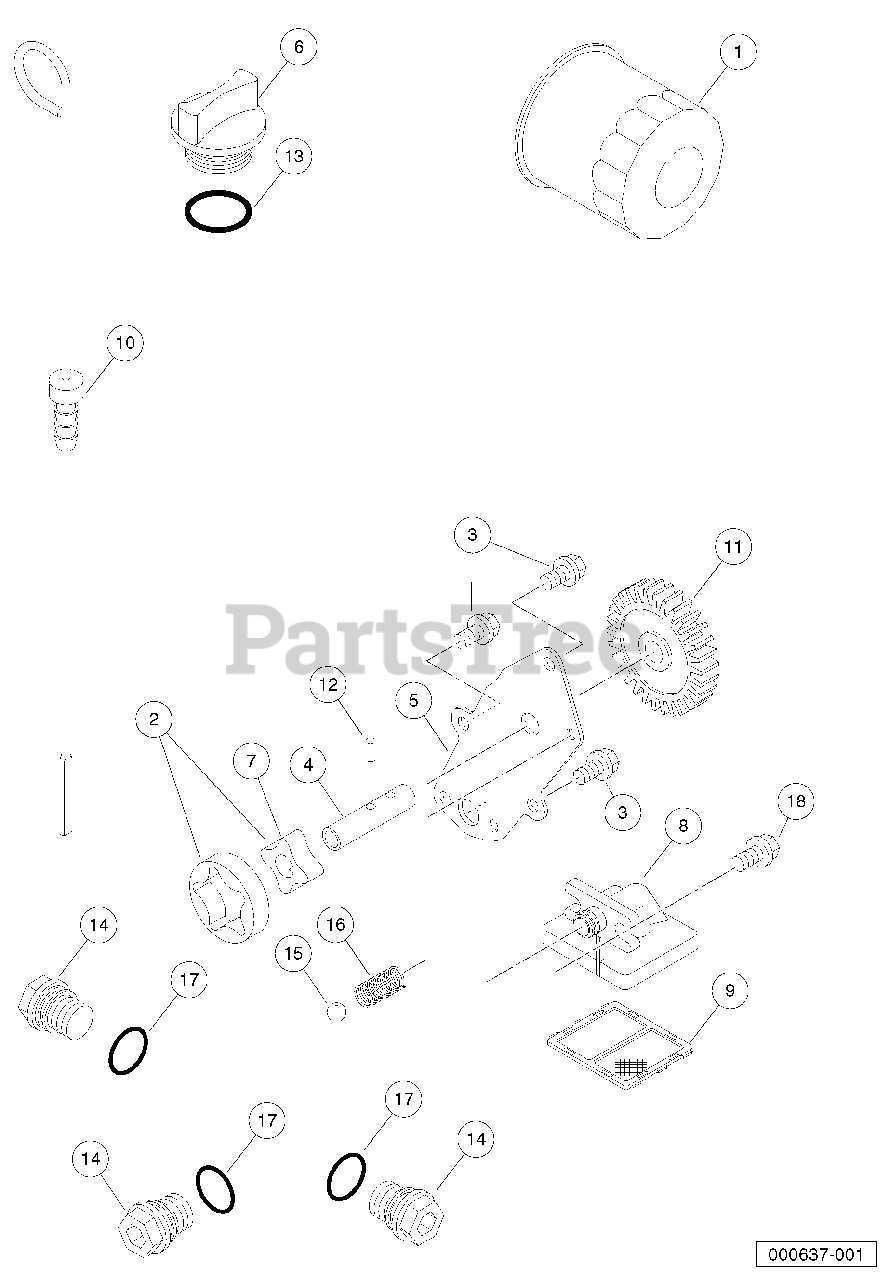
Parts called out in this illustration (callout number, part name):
1	Filter, Oil
2	Oil Pump And Rotor
3	Bolt, Flg, M6 X 1.0 X 12
4	Shaft, Oil Pump, Fh
5	Plate, Oil Pump, Fh
6	Cap, Oil, Fill, Fh
7	Rotor, Pump, Oil, In, Fh
8	Pickup, Oil, Fh
9	Screen, Pickup, Oil, Fh
10	Gauge, Oil, Fh
11	Gear, Spur, Oil Pump, Fh
12	Pin, Oil Pump, Fh
13	O-ring, Cap, Oil, Fill, Fh
14	Plug, Oil Drain, Fh
15	Ball, Oil Pump, Fh
16	Spring, Oil Pump, Fh
17	O-ring, Drain Plug, Oil, Fh
18	Bolt, Oil Pickup, Fh
